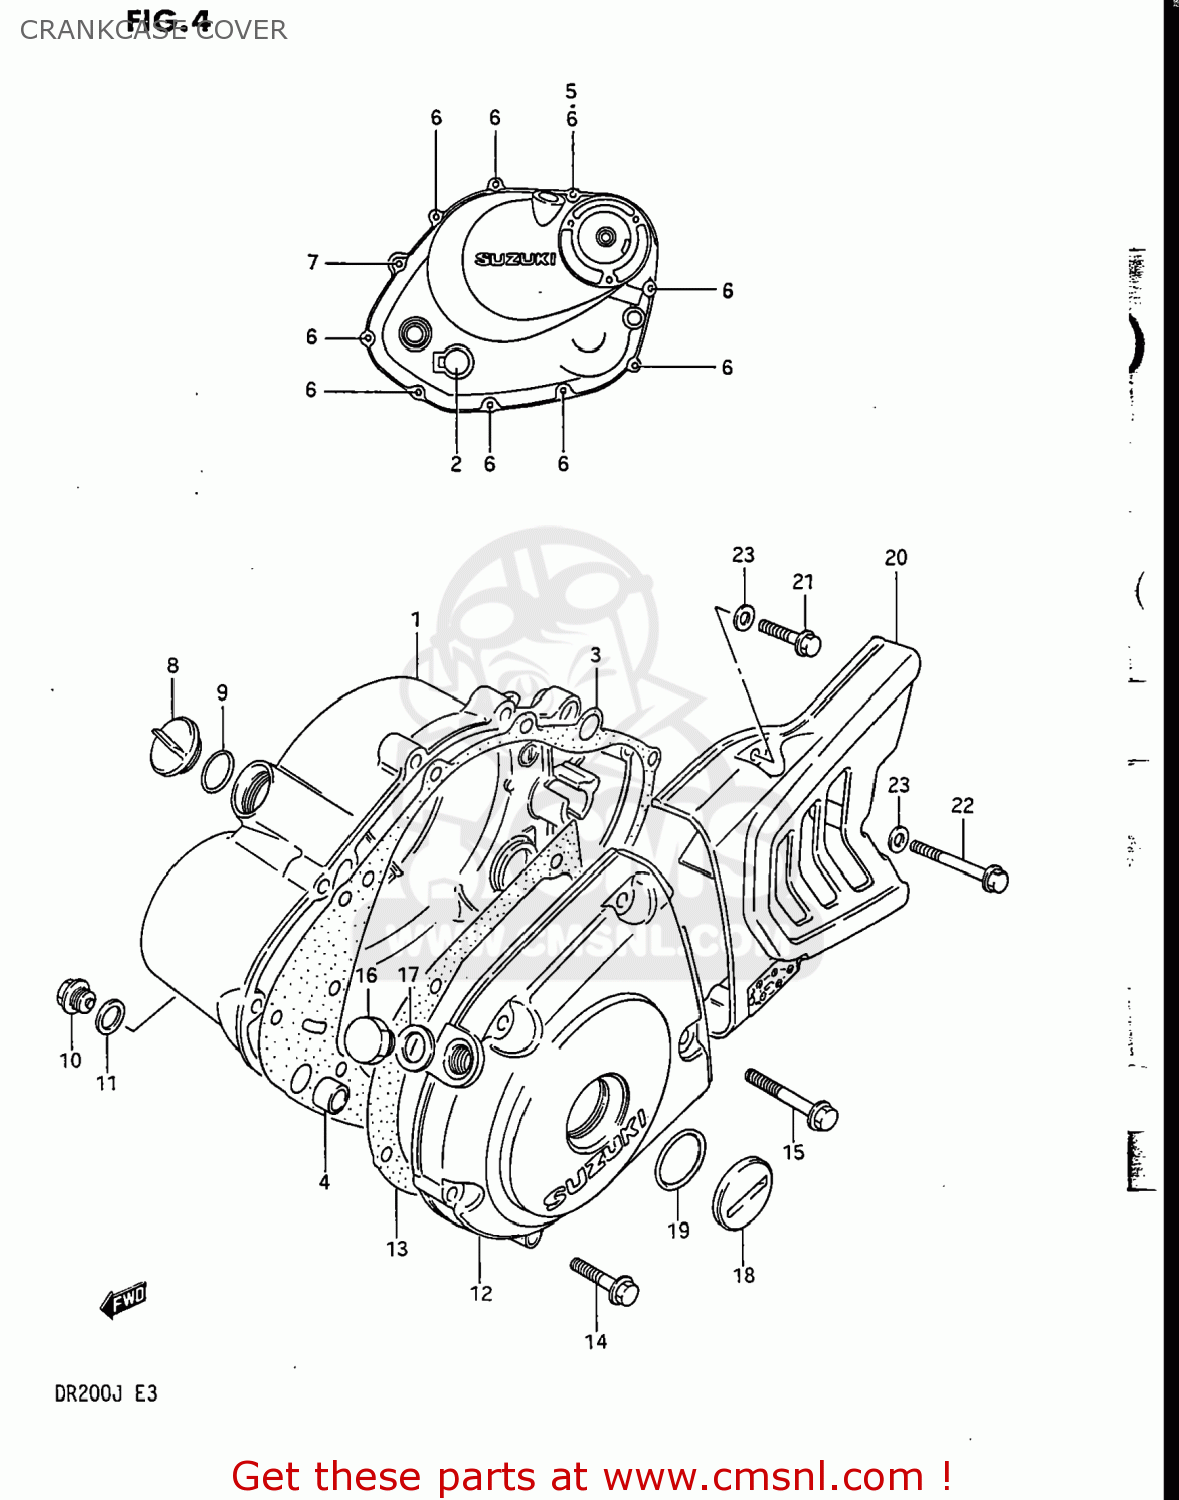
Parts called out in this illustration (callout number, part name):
1	COVER,CLUTCH
2	LENS,OIL LEVEL CHECK
3	GASKET,CLUTCH COVER (MCA)
4	PIN
5	WASHER
6	BOLT 6X30
7	BOLT
8	PLUG
9	O RING(D:3.1,ID:16.8)
10	PLUG(14X12)
11	GASKET(14X19.2X2) (NAS)
12	COVER,MAGNETO
13	GASKET,MAGNETO COVER (MCA)
14	BOLT 6X30
15	BOLT 6X40
16	PLUG(12X9)
17	GASKET(12.1X16.2X3.7) (NAS)
18	PLUG
19	O RING(D:3.1,ID:22.7)
20	COVER,SPROCKET
21	BOLT
22	BOLT
23	WASHER,5MM
